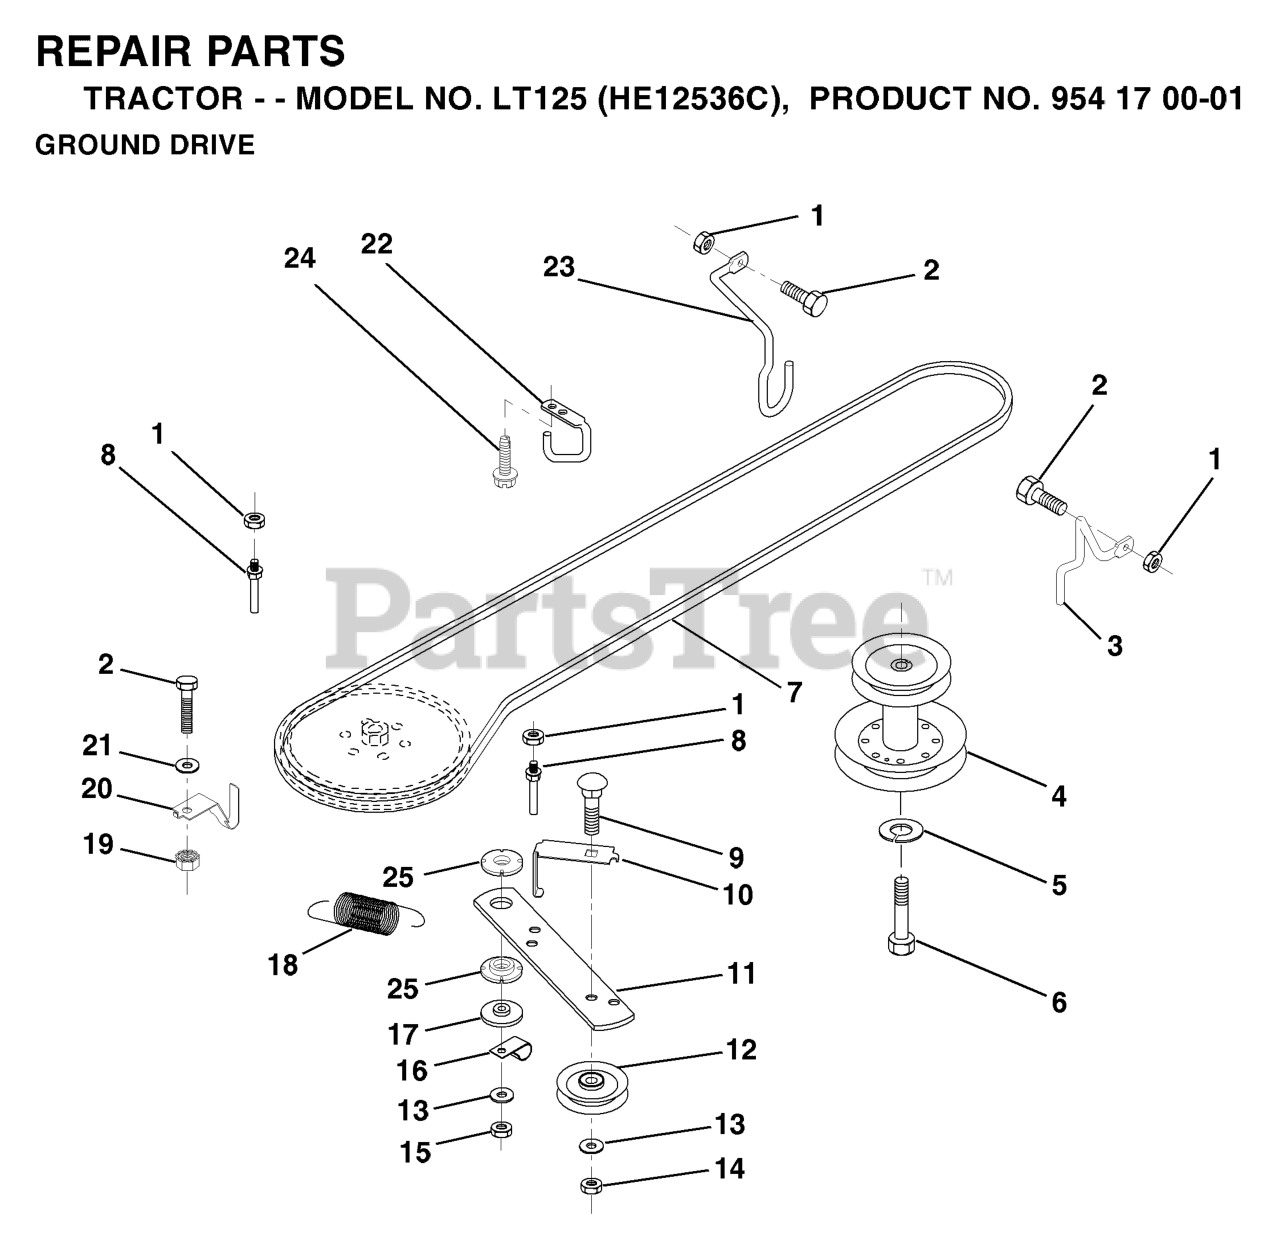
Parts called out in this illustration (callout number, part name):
1	LOCKNUT
2	BOLT
3	KEEPER/MOWER DRIVE RH
4	PULLEY.ENGINE.36/38 LR
5	LOCKWASHER
6	Bolt, Hex Hd. 7/16-20 UNF Grade 5
7	BELT
8	KEEPER,DRIVE BELT
9	Bolt, Carriage 3/8-16 UNC x 1-1/2
10	KEEPER.BELT.GROUND.DRIVE.IDLER
11	ARM, GROUND DRIVE CLUTCH
12	PULLEY.IDLER.FLAT
13	WASHER
14	LOCKNUT
16	CLIP,INSULATOR
17	SPACER, RETAINER
18	SPRING.EXTENSION
19	NUT
20	KEEPER-T/A GROUND DRIVE BELT
21	Washer 11/32 x 5/8 x 16 Ga SD
22	KEEPER,FRA DR BEL
23	KEEPER-MOWER DRIVE LH
24	SCREW
25	BUSHING NYLON COLLERED
